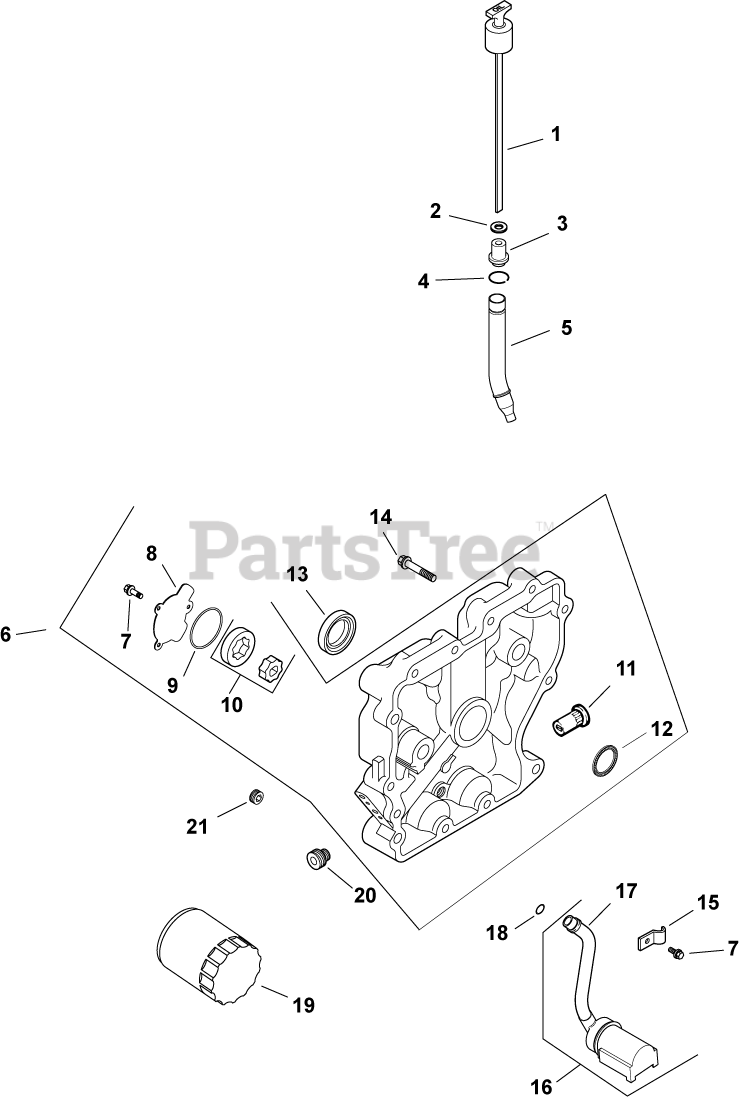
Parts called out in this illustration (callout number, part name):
1	DIPSTICK - DISCONTINUED
3	SEAL USE 25 032 13-S
5	TUBE, OIL FILL - DISCONTINUED
6	PLATE, CLOSURE & BEARING
7	SCREW,FLG THD FRM M5X0.8X16-(#25086398S)
8	COVER, OIL PUMP
9	O-RING (1.78" DIA)
10	PUMP ASSEMBLY, OIL
11	VALVE, OIL PRESSURE RELIEF
12	BEARING, CRANKSHAFT
13	SEAL, OIL
14	SCREW, FLG M8X1.25X45
16	KIT, OIL PICK-UP
17	PICK-UP, OIL SCREEN
18	O-RING (.5" DIA)
19	OIL FILTER
20	NIPPLE, OIL FILTER
21	PLUG, CTSK PIPE 1/8"
